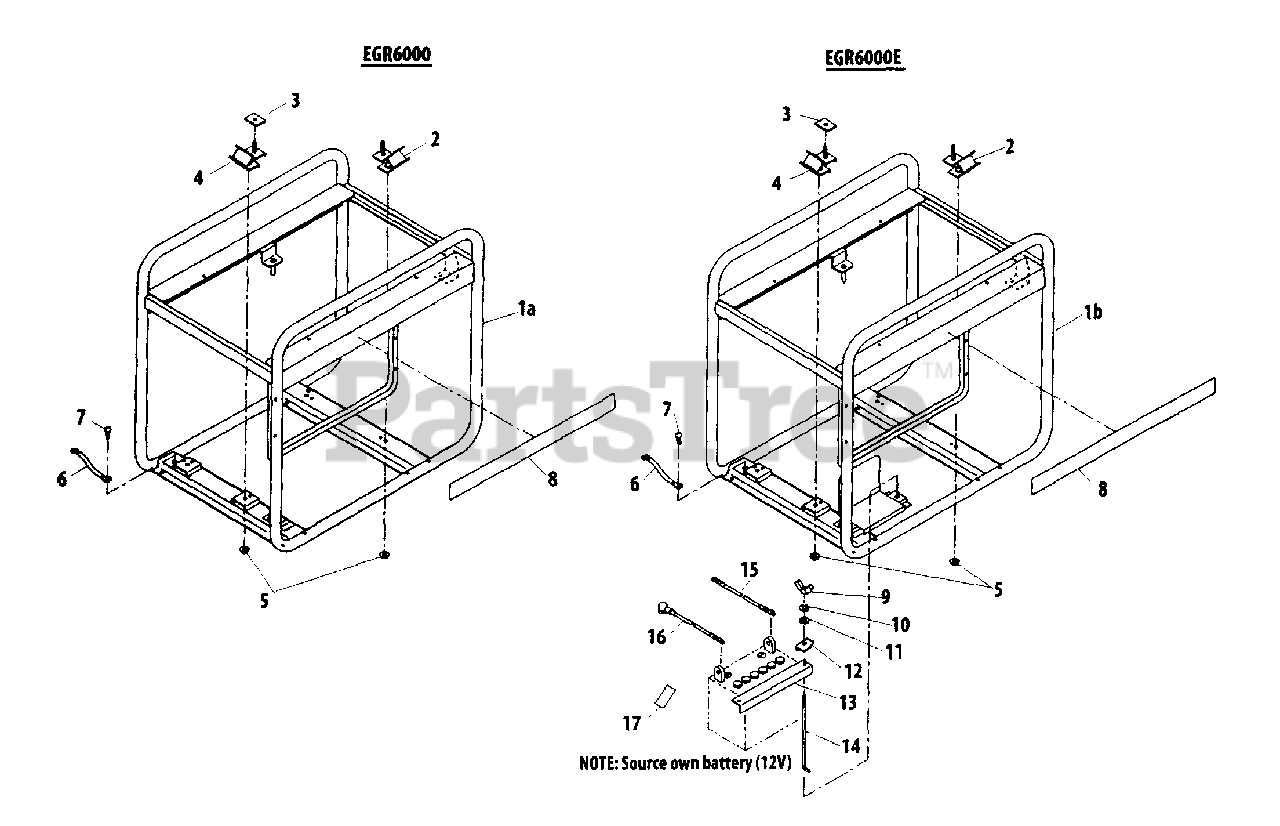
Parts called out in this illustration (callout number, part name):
1A	FRAME
1B	FRAME
5	NUT - 8 -- FLANGE
6	LEAD - ANTI-STATIC
8	LABEL - MODEL
9	WINGNUT
10	LOCKWASHER - 6
11	WASHER - 6
12	SPACER
13	STAY, BATTERY
14	BOLT, BATTERY
15	WIRE
16	WIRE
17	LABEL
